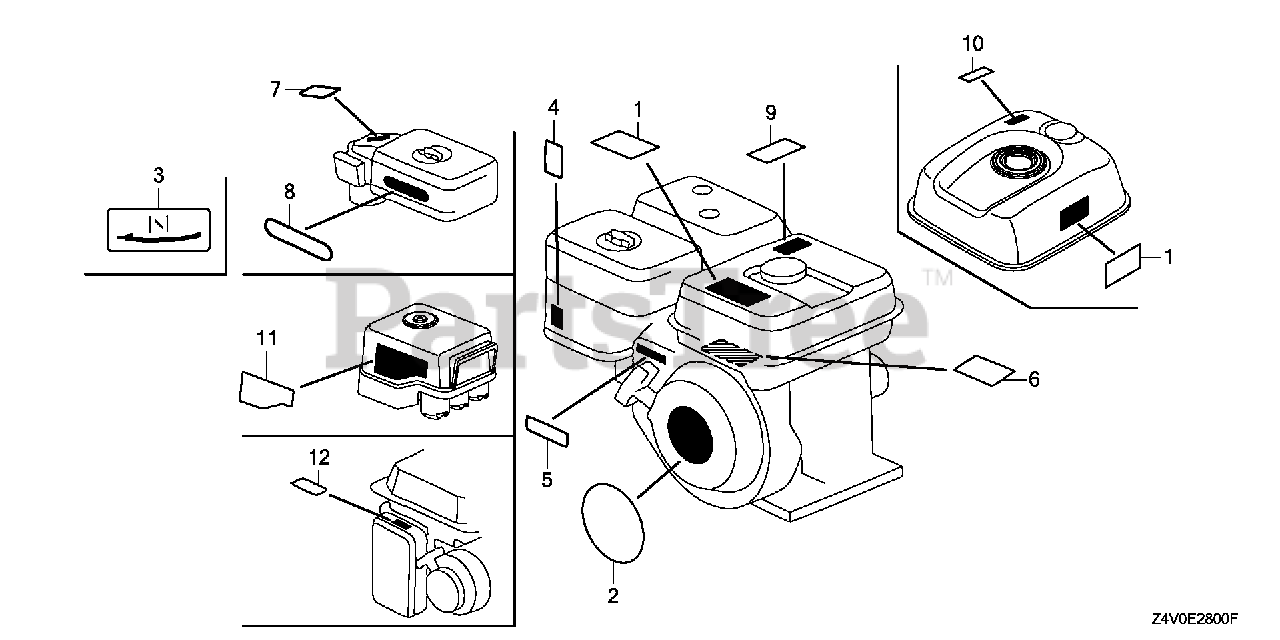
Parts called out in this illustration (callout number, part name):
1	MARK, OPERATOR CAUTION (ENGLISH)(MADE IN THAI)
2	EMBLEM (GX200)
4	MARK, CHOKE
5	MARK, THROTTLE INDICATION
10	MARK, EX. CAUTION (ENGLISH)
11	MARK, SALES POINT
